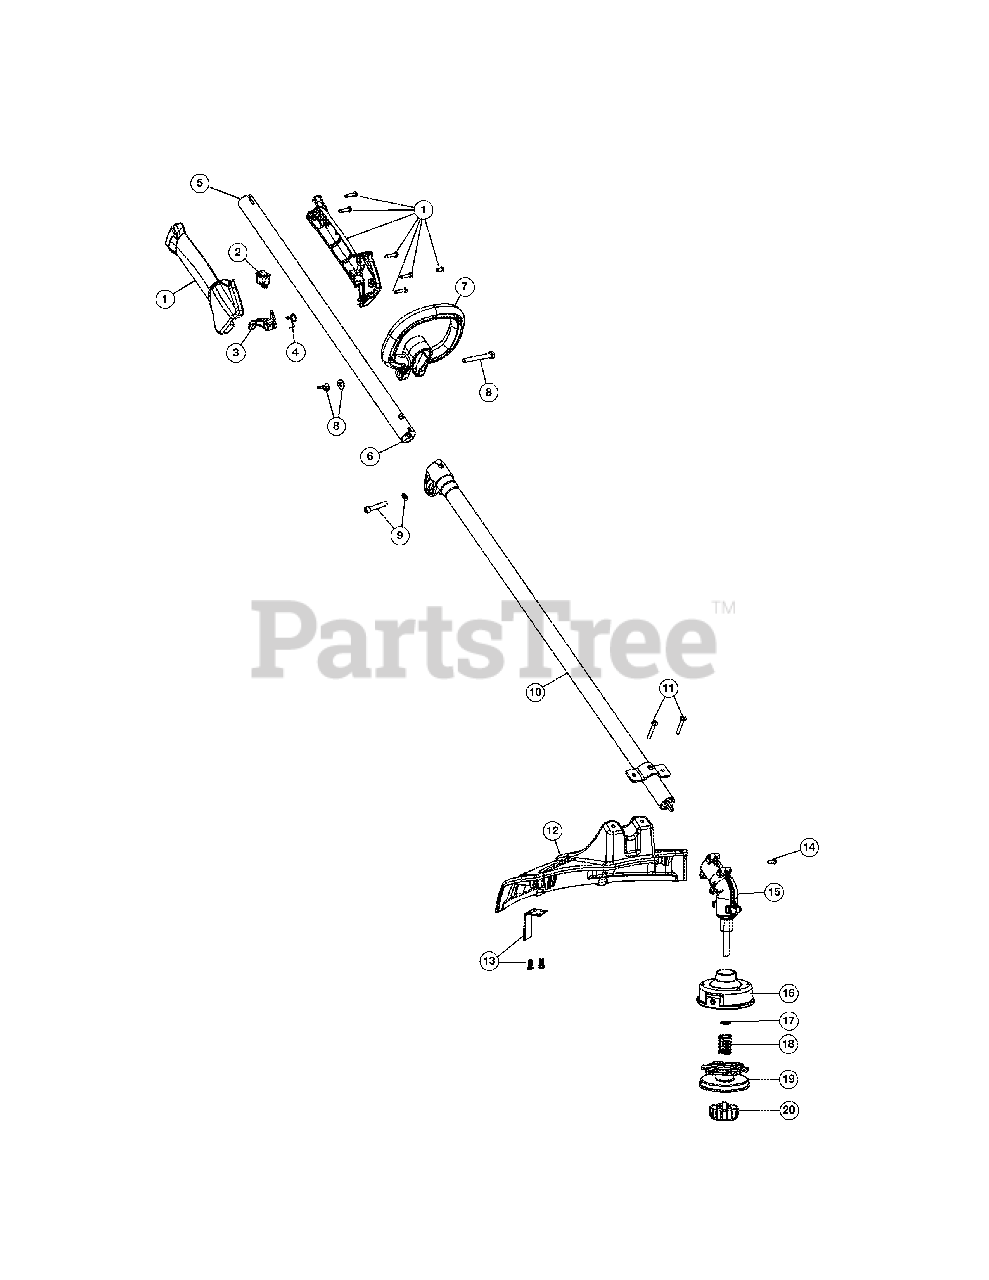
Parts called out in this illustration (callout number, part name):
1	Throttle Housing Assembly (includes 2-4)
3	Throttle Trigger
4	Throttle Trigger Spring
5	Upper Shaft Housing Assembly (includes 6)
6	Upper Flexible Drive Shaft
7	D-Handle (includes 8)
8	D-Handle Hardware Assembly
9	Clamp Hardware
10	Lower Shaft Housing Assembly
11	Shield Mounting Screw
12	Shield Assembly (includes 11 & 13)
13	Blade Assembly
14	Anti-Rotation Screw
15	Gearbox Assembly (includes 15-20)
16	Outer Spool Assembly (includes 17)
17	Retainer
19	Inner Reel
20	Bump Head Knob Assembly
